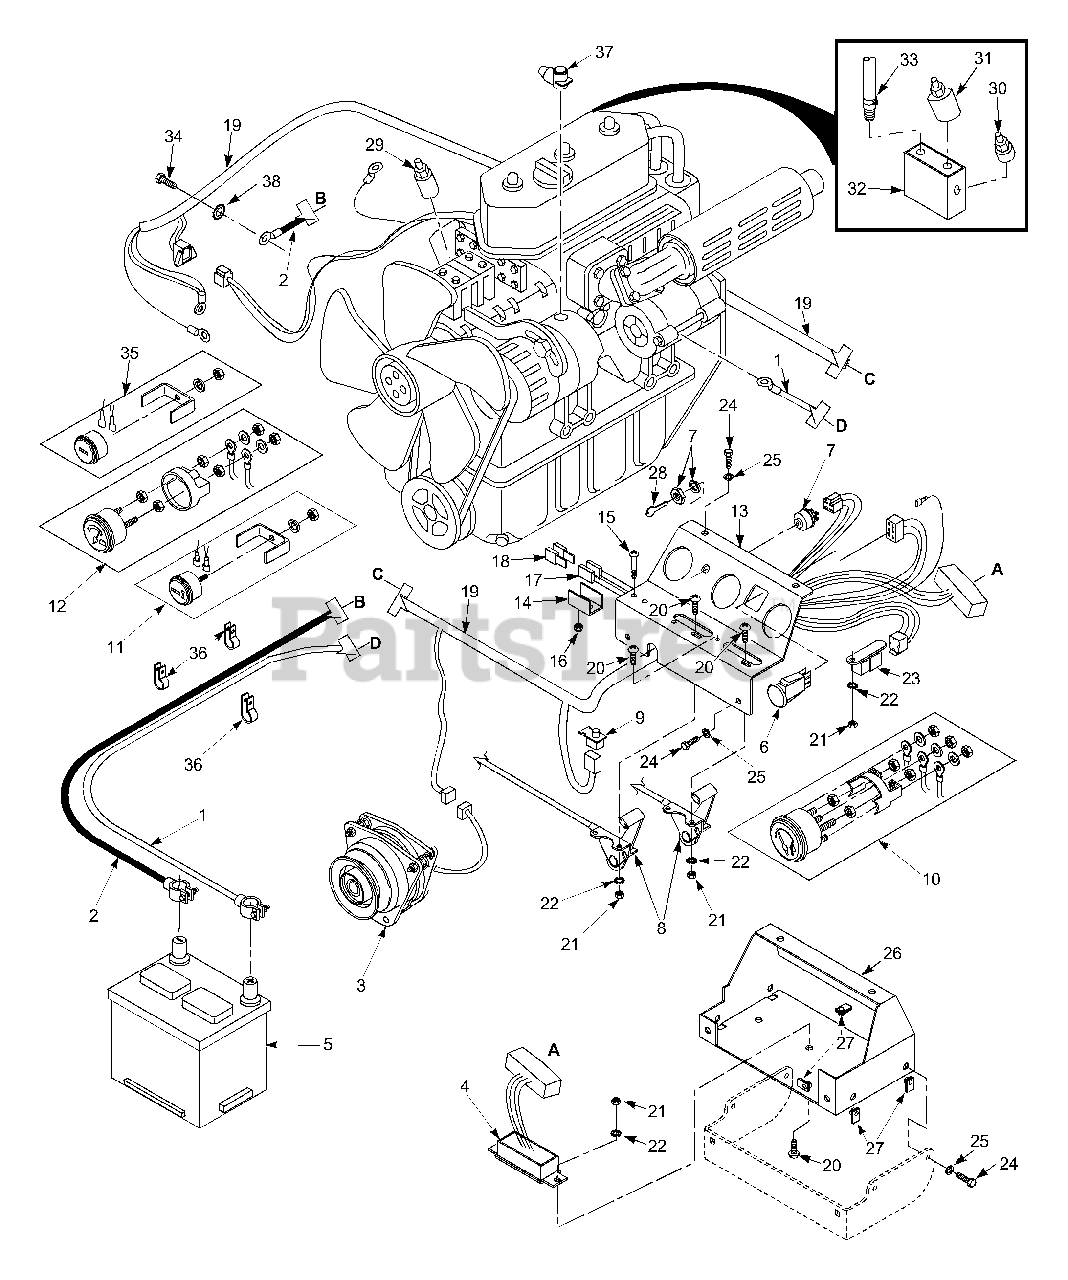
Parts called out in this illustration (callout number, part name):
1	Cable, Positive Battery
2	Cable, Negative Battery
3	Clutch, Electric PTO
4	Module, Interlock
5	Battery
6	Switch, PTO
7	Switch, Key
8	Cable, Control (Throttle, Choke)
9	Switch, Seat
10	Gauge, Water Temperature
11	Gauge, Oil Pressure
12	Gauge, Volts
13	Panel, Instrument Panel
14	Bracket, Fuse Holder
15	Screw, #10-32 x 1.5" Phillips
16	Nut, #10-32 Elastic Stop
17	Fuse Holder w/ 20 Amp Fuse
18	Fuse, 20 Amp
19	Harness, Wiring
20	Screw, #10-32 x .5" Phillips
21	Nut, Hex #10-32
22	Lock Washer #10
23	Relay
24	Bolt, Hex Head 1/4-20 x .75"
25	Lock Washer 1/4"
26	Base, Instrument Panel
27	U-Nut, 1/4-20
28	Key & Ring Assembly
29	Sender Unit, Water Temperature
30	Switch, Low Oil Pressure
31	Sender Unit, Oil Pressure
32	Manifold, Oil
33	Hose, Oil Pressure Sender
34	Bolt, Hex Head M8-1.25 x 14
35	Hour Meter
36	Clamp, Cable .5" ID
37	Boot, Positive Battery Terminal
38	Washer, Star
